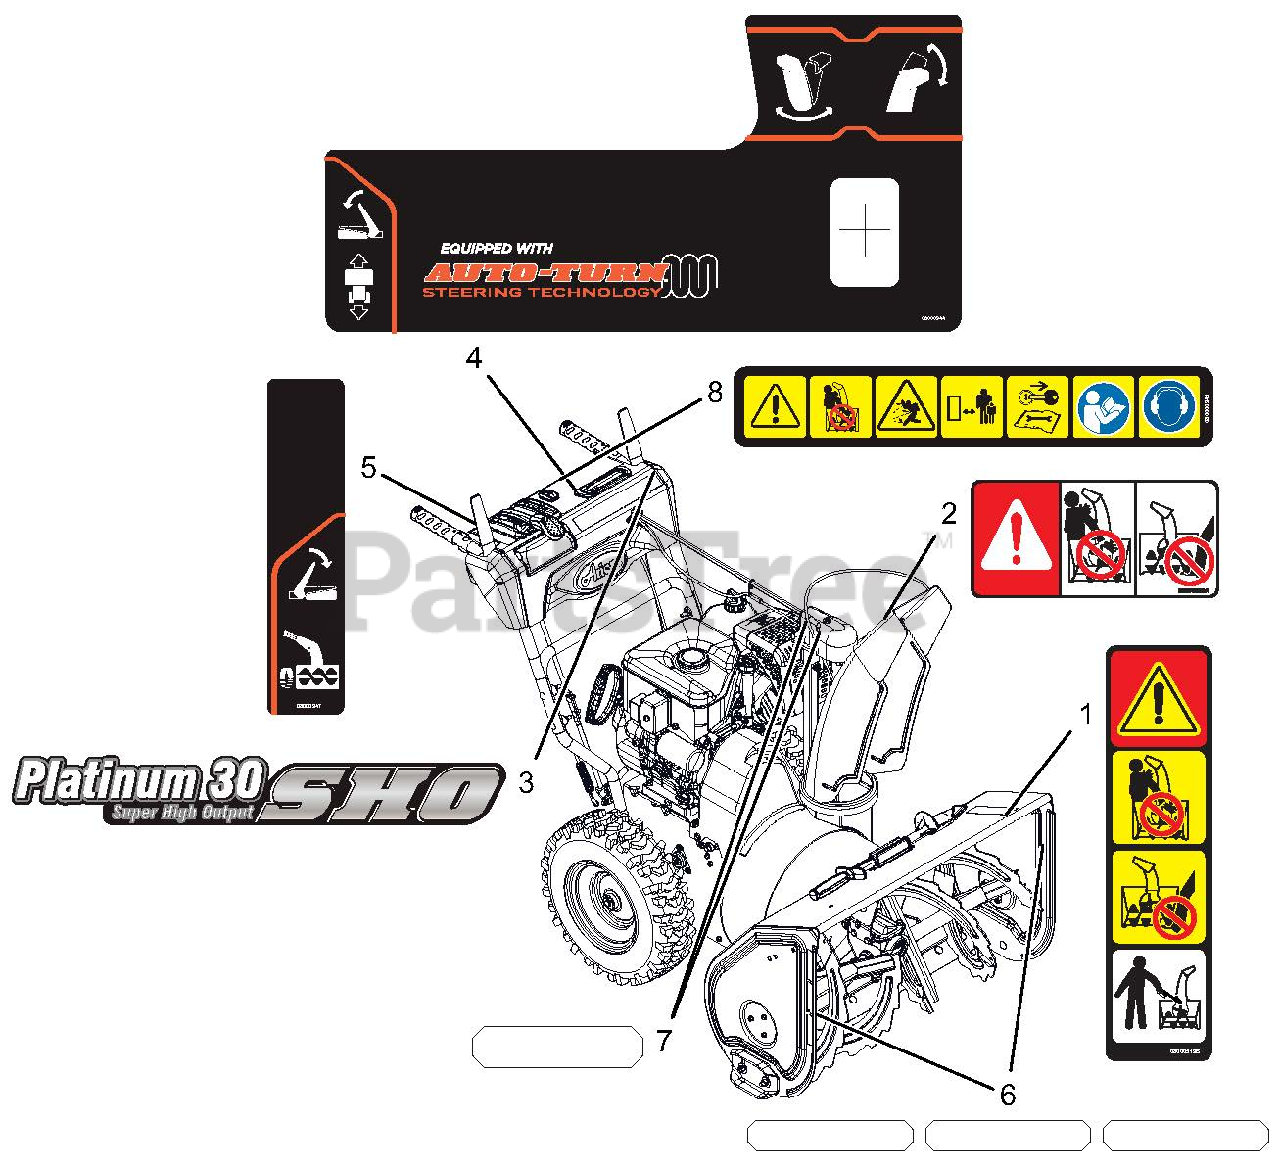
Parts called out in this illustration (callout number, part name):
1	DECAL, DANGER - ROTATING PARTS
2	DECAL, DANGER
3	DECAL,DASH-PLATINUM 30 SHO
4	DECAL,CONTROL-LG QT2
5	DECAL,CONTROL-RH CONTROL
6	DECAL,REFLECTIVE,HOUSING
7	DECAL,REFLECTIVE,GEAR COVER
8	DECAL,DASH - SAFETY
